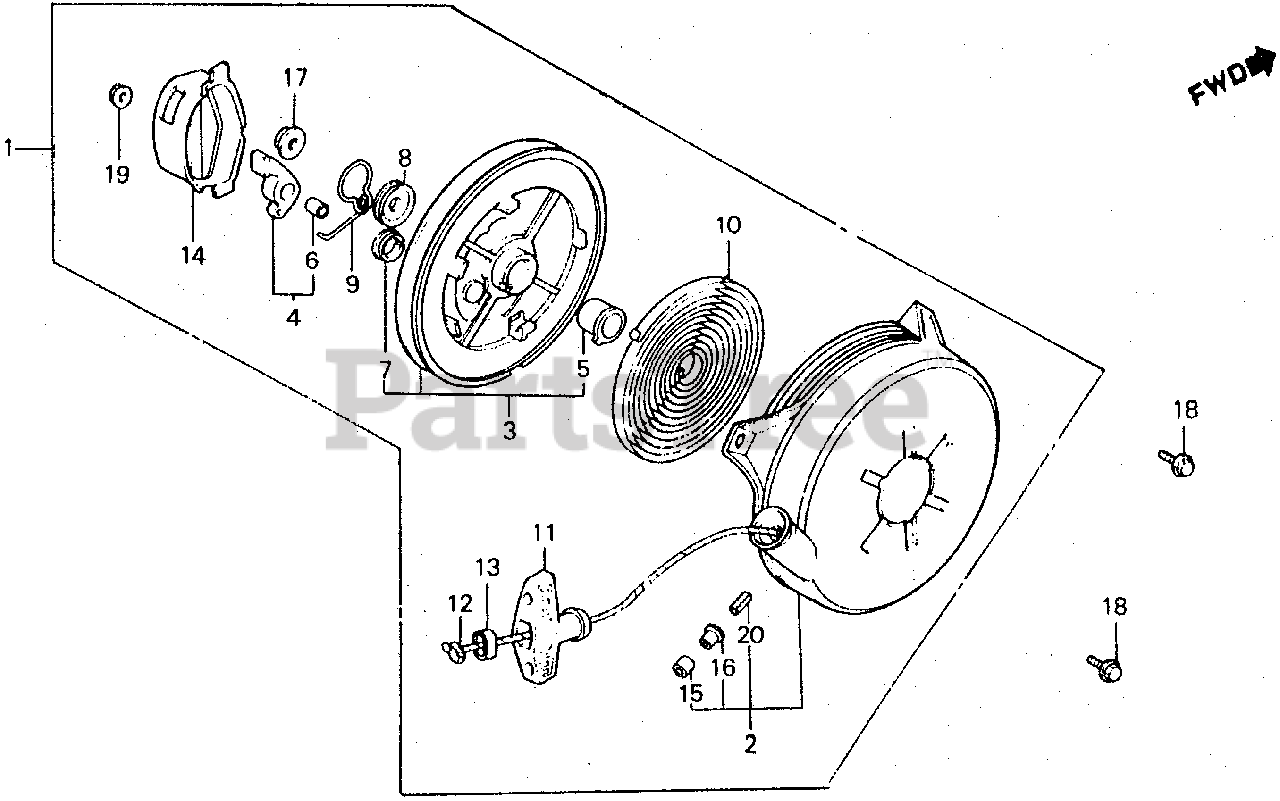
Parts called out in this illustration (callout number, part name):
1	STARTER ASSY., RECOIL *R8* (BRIGHT RED)
2	CASE, STARTER *R8* (BRIGHT RED)
3	REEL, STARTER
5	BOSS, REEL
6	BUSH, RATCHET
7	BUSH, REEL STARTER
8	PLATE, FRICTION
9	SPRING, FRICTION
10	SPRING, RETURN
11	GRIP, STARTER
12	ROPE, RECOIL STARTER (#5X55")
12	ROPE, STARTER (#5X55")
13	SUPPORT, GRIP
14	COVER, REEL STARTER
15	ROLLER, GUIDE
16	BUSH, ROLLER
17	NUT, SELF-LOCK (8MM)
18	BOLT-WASHER (6X10)
19	NUT, FLANGE (5MM)
20	PIN, SPRING (3X18)
